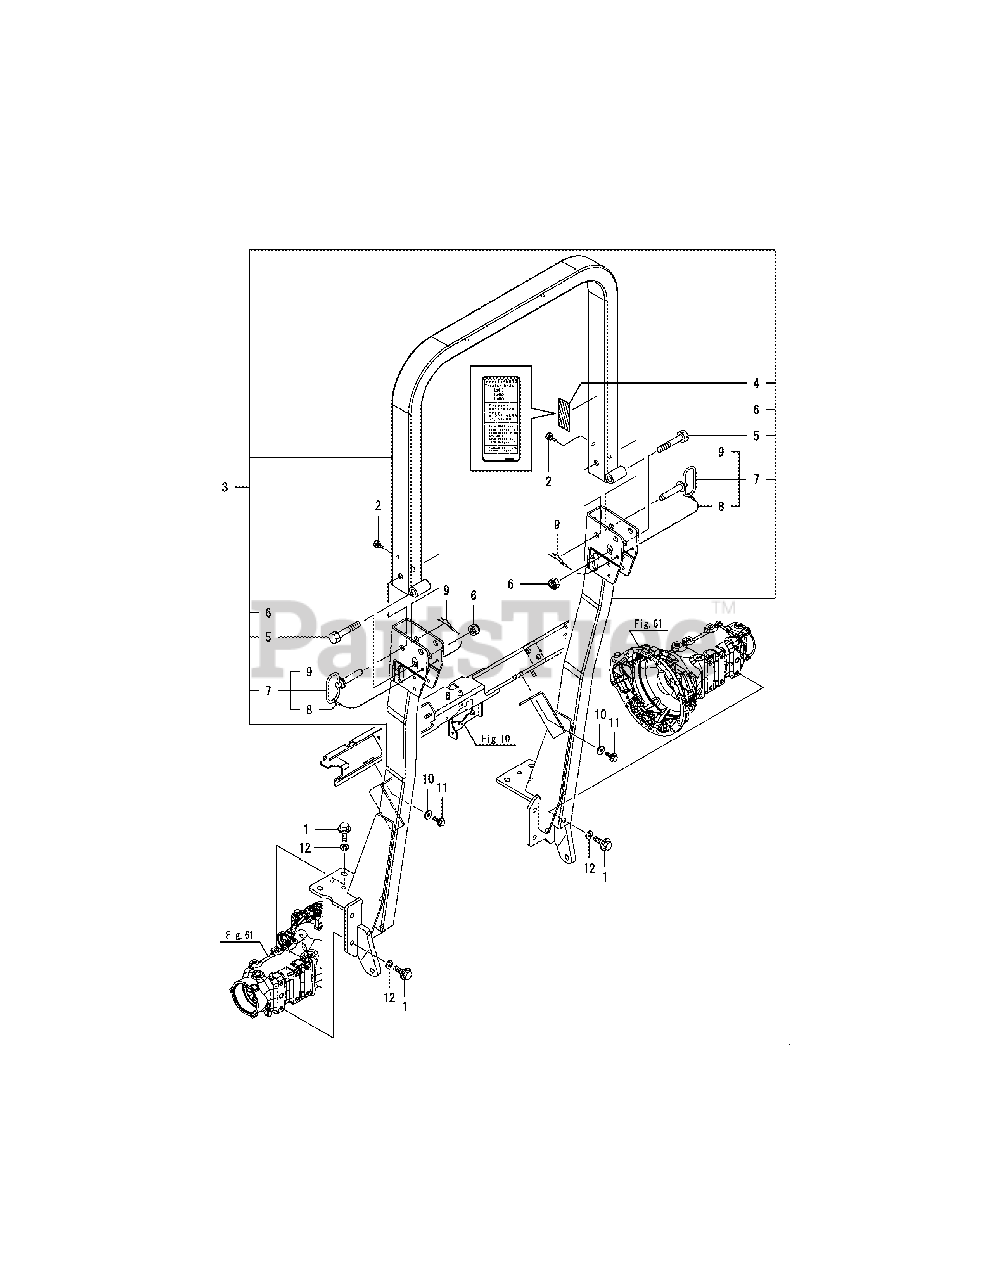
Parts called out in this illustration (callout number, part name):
2	STOPPER, PEDAL
4	LABEL,ROPS STANDARD
6	NUT, M16 (NYLOCK
7	PIN ASSY, STOPPER
8	PIN STOPPER CMP
9	HITCH PIN CLIP
11	BOLT M 8X 20 PLATED
12	SPRING WASHER 12
